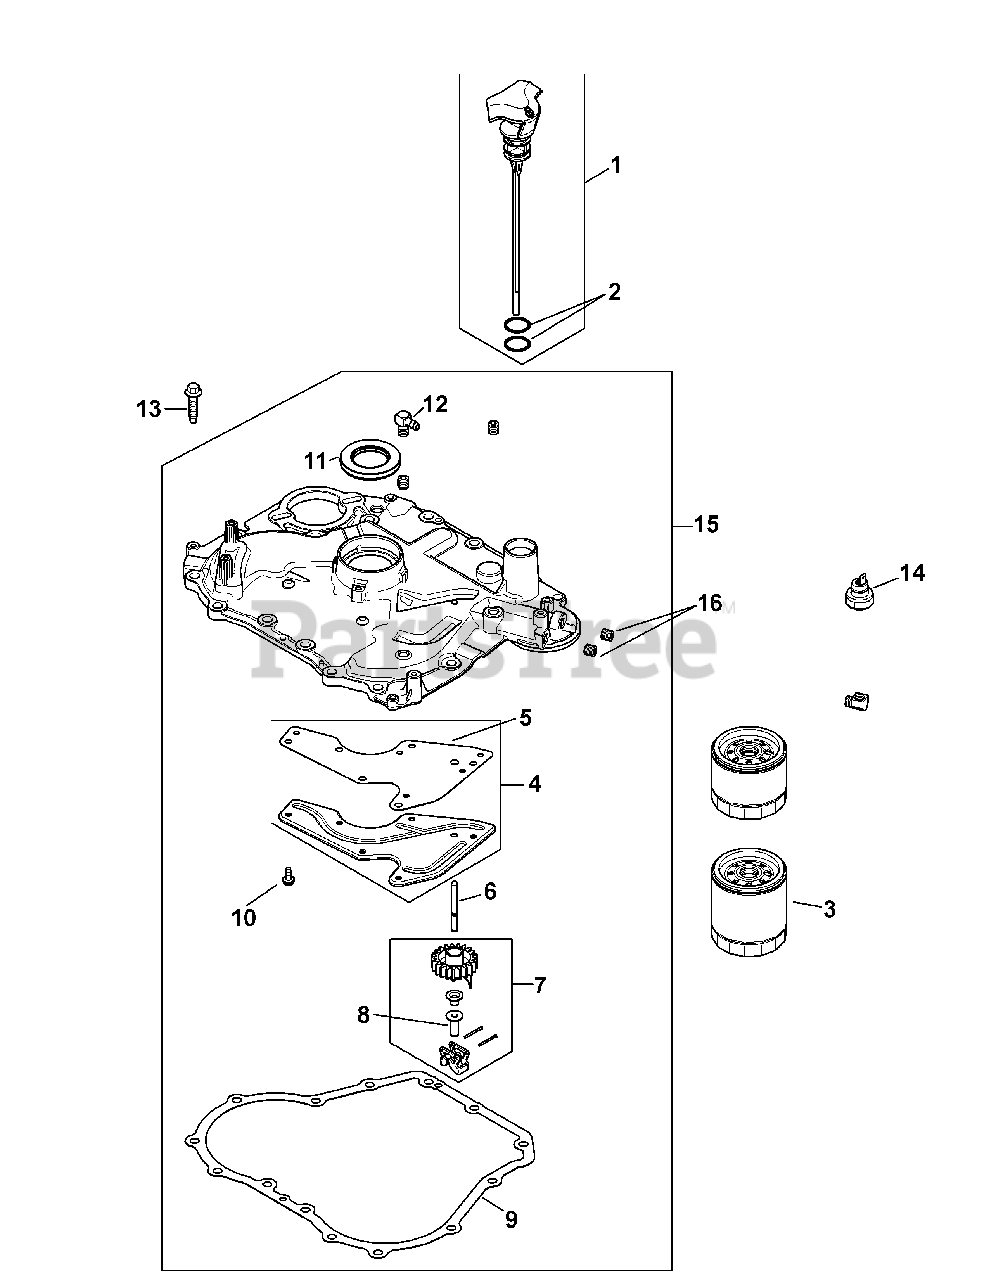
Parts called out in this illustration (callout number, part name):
1	Dipstick Assembly (Inc. 2)
2	O-Ring
3	Oil Filter
4	Oil Passage Cover Kit (Inc. 5)
5	Oil Passage Gasket
6	Governor Cross Shaft
7	Governor Gear Assembly
8	Governor Regulating Pin
9	Closure Plate Gasket
10	Flg. Thd. Frm. Screw, M5 x 0.8 x 13
11	Oil Seal
12	90° Hose Connector
13	Hex Flange Screw, 1/2
14	Oil Pressure Switch
15	Closure Plate Assembly Kit
16	Ctsk. Pipe Plug, 1/8
